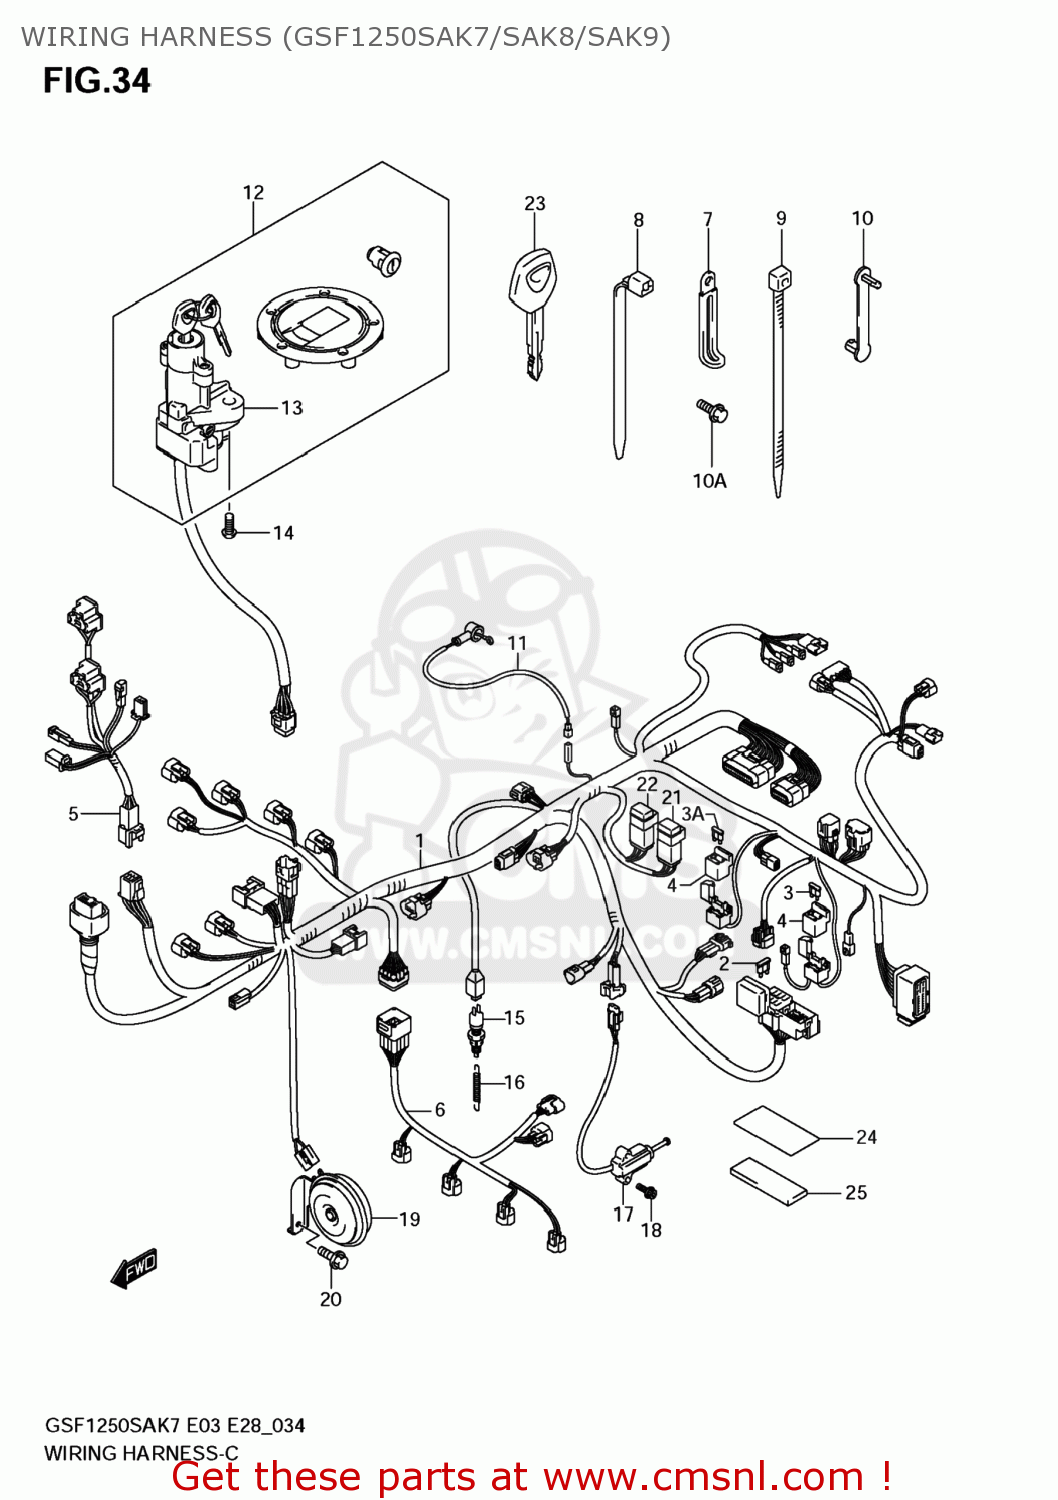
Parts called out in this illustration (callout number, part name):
1	HARNESS,WIRING NO.1
2	FUSE(10A)
3	FUSE(15A)
3A	FUSE(20A)
4	HOLDER,FUSE
5	HARNESS,WIRING NO.2
6	WIRE,INJECTOR LEAD
7	CLAMP(L:45)
8	CLAMP(L:95)
9	CLAMP(L:145)
10	CLAMP(L:33)
10A	BOLT
11	WIRE,OIL PRESSURE SWITCH LEAD
12	LOCK SET
13	LOCK ASSY,STEE
14	BOLT(8X20)
15	SWITCH ASSY,STOP LAMP
16	SPRING
17	SWITCH ASSY,SIDE STAND
18	BOLT
19	HORN ASSY
20	BOLT
21	RELAY ASSY
22	RELAY ASSY
23	KEY,BLANK
24	TAPE,RR FENDER
25	PROTECTOR(20X90)X2
